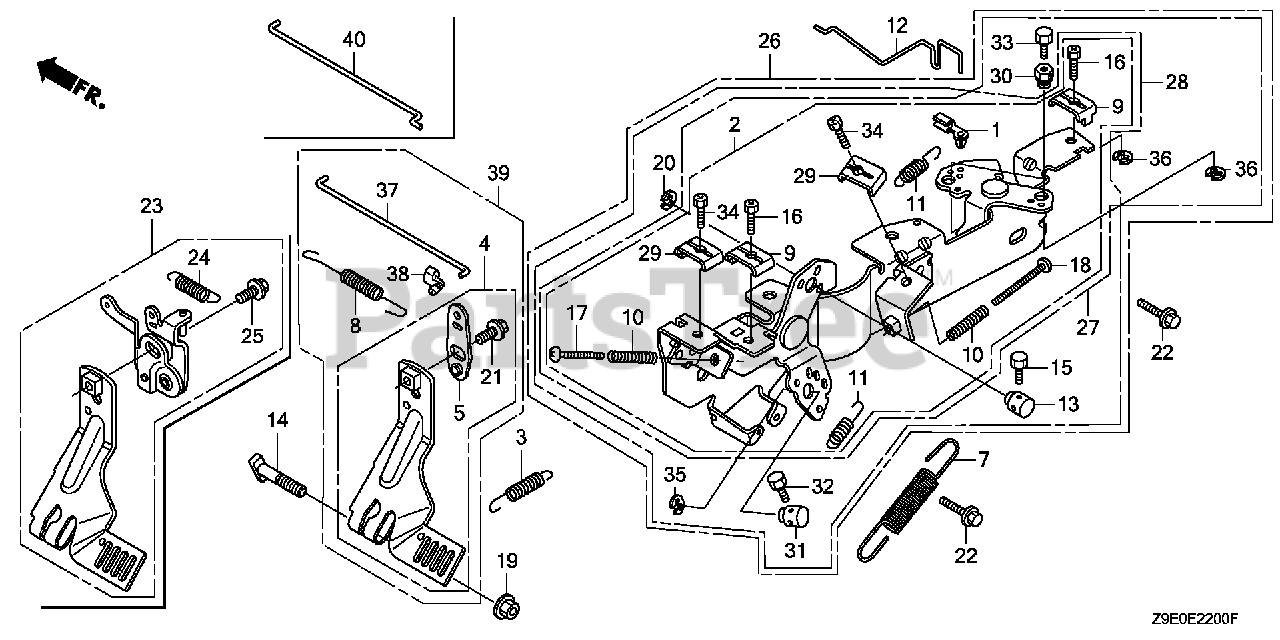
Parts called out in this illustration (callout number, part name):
1	JOINT, ROD
3	SPRING, STARTER
4	ARM, GOVERNOR
7	SPRING, GOVERNOR
8	SPRING, THROTTLE RETURN
9	HOLDER, CABLE
10	SPRING, CONTROL ADJUSTING
11	SPRING, CABLE RETURN
12	ROD, CHOKE CONTROL
13	HOLDER, CABLE
14	BOLT, GOVERNOR ARM
15	BOLT, RECESSED (4X6)
16	BOLT, RECESSED (5X16)
17	SCREW, PAN (5X30)
18	SCREW, PAN (5X45)
19	NUT, FLANGE (6MM)
20	E-RING (5MM)
21	BOLT, FLANGE (6X10)
22	BOLT, FLANGE (6X14)
28	CONTROL ASSY.
29	HOLDER, CABLE
31	HOLDER, CABLE
32	BOLT, RECESSED (4X6)
34	BOLT, RECESSED (5X16)
35	E-RING (5MM)
37	ROD, GOVERNOR
38	BUSH, LINKAGE
